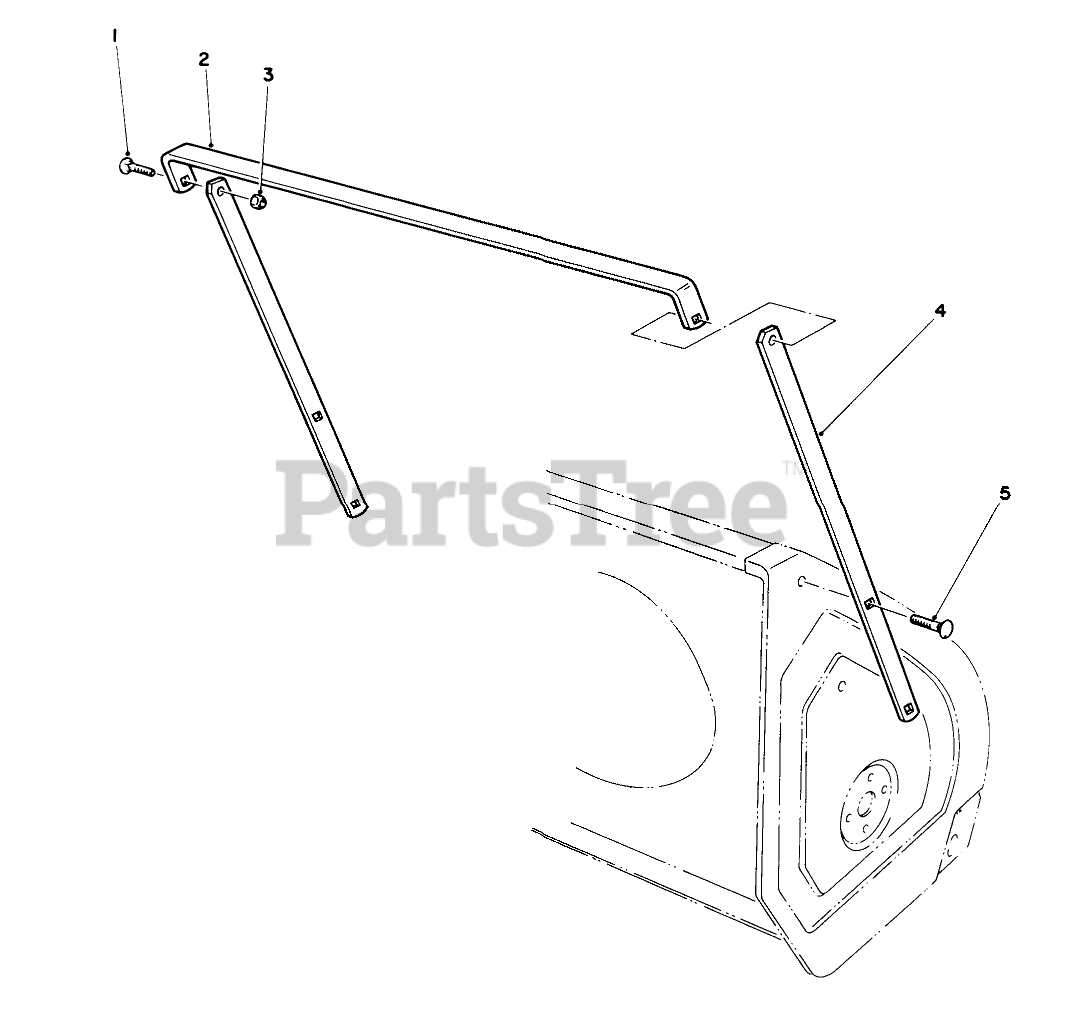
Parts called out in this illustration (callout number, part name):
1	SCREW-CARR
3	NUT-LOCK, NI
4	Breaker-Side
5	BOLT-CARR
